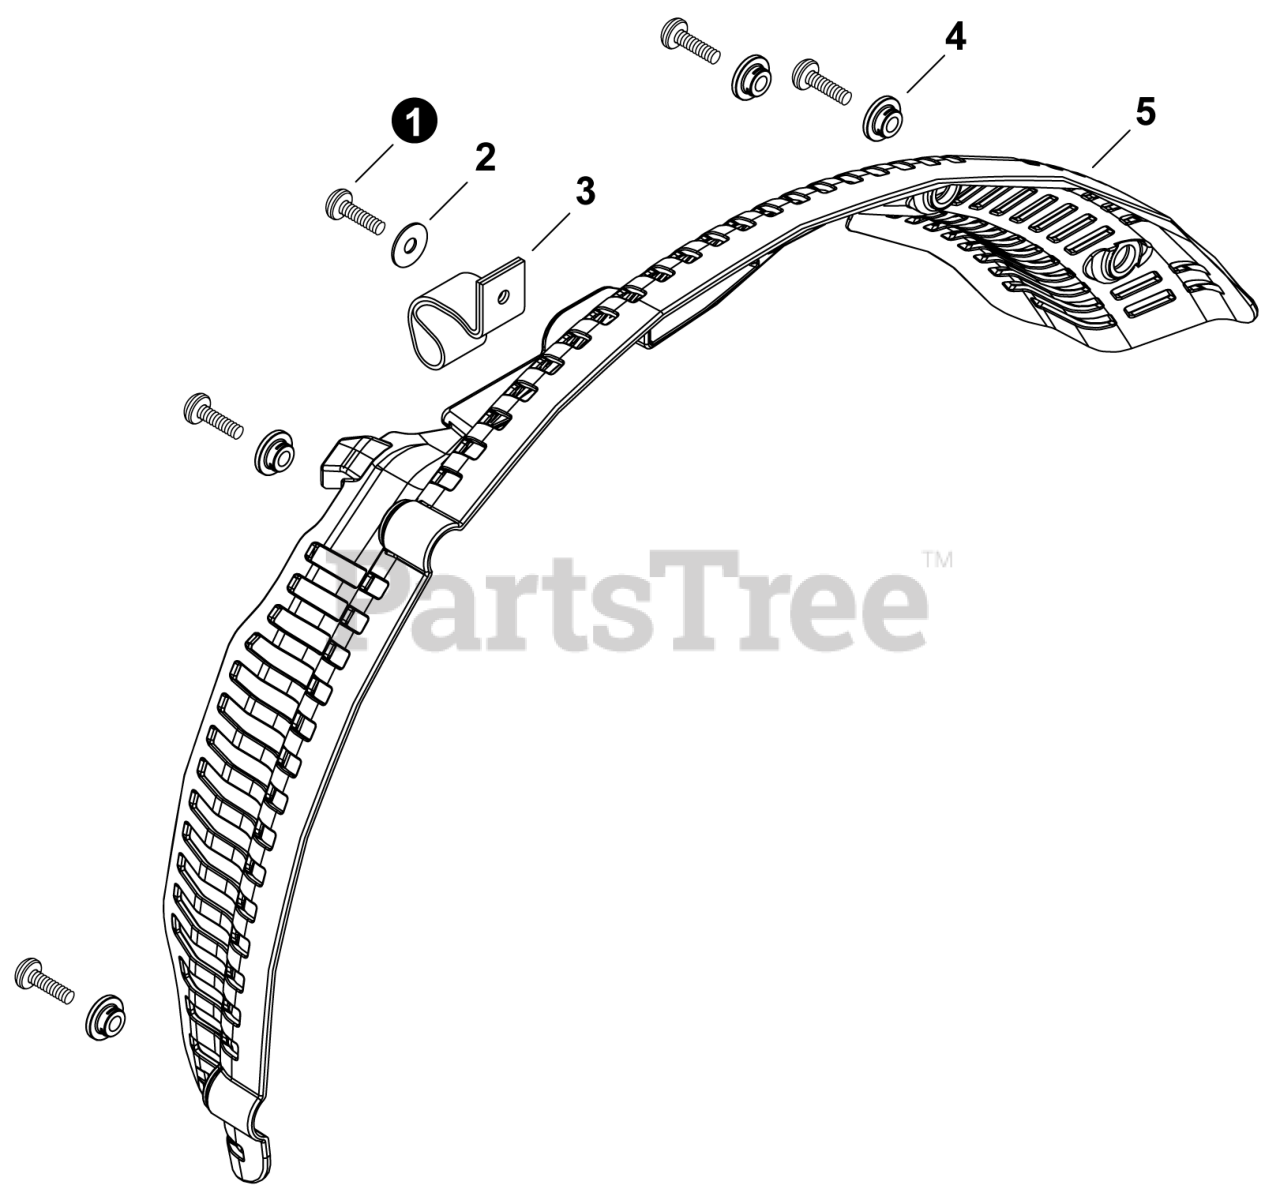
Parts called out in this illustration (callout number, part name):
1	BOLT, TORX 5x20
2	WASHER 5.5x16x0.8
3	STRAP, SAFETY
4	COLLAR 5
5	GUARD, LEAF
